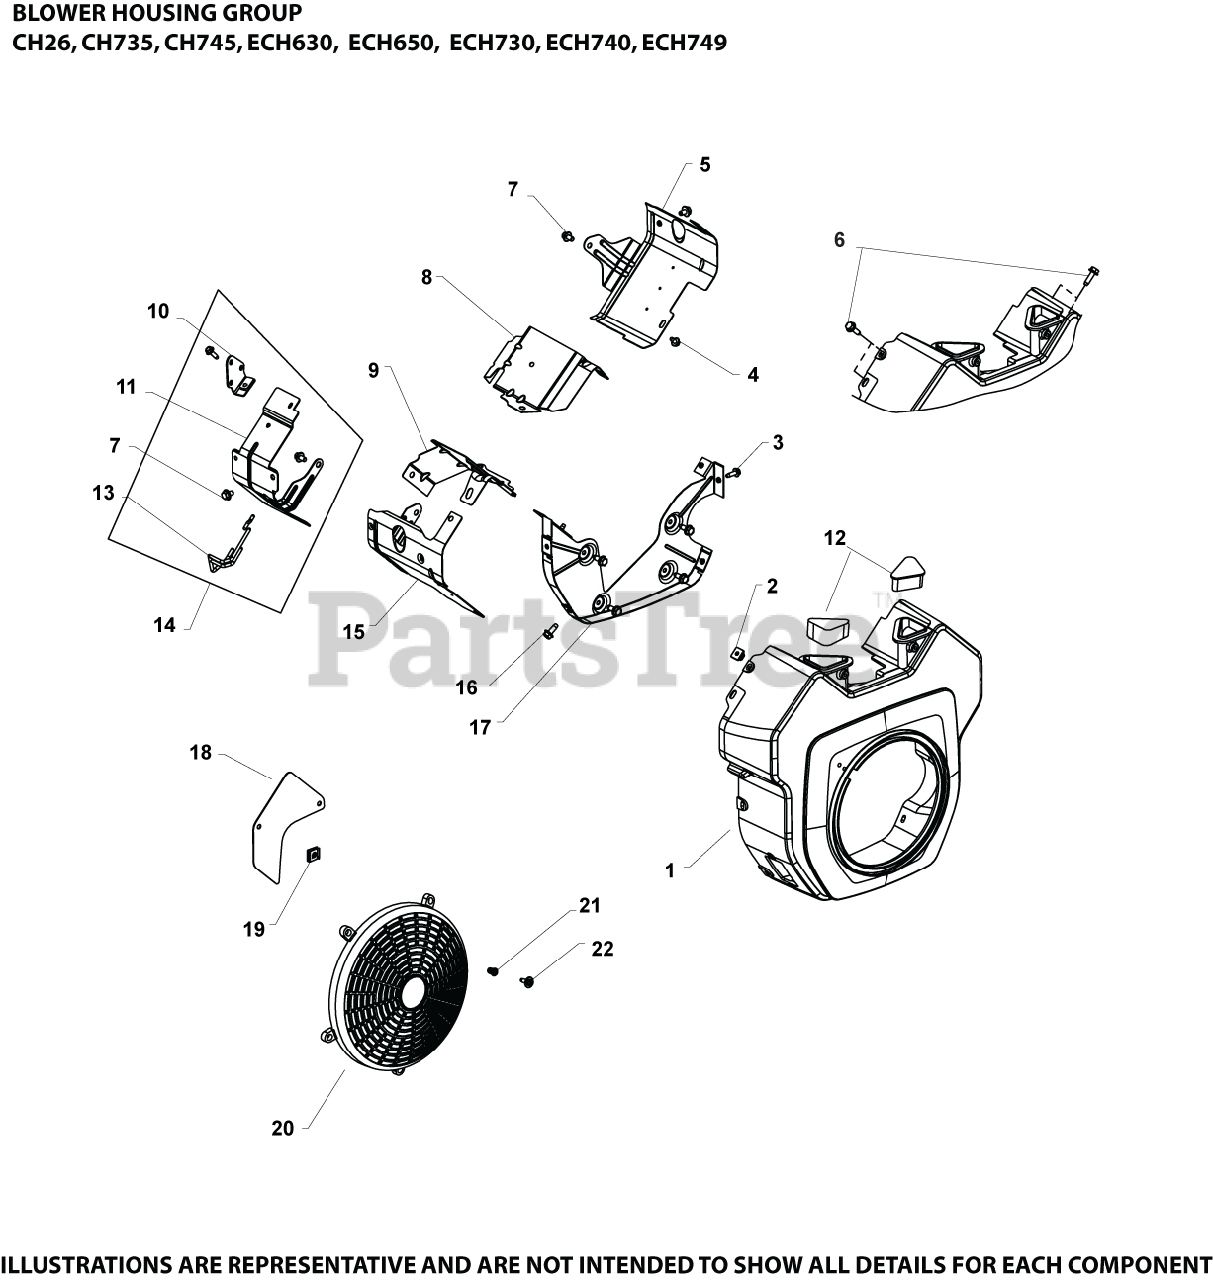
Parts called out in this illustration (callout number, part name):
1	HOUSING, BLOWER
3	SCREW, THREAD FORMING
4	SCREW, THREAD FORMING
5	BAFFLE, BARREL
6	SCREW, THREAD FORMING
8	BAFFLE, VALLEY #1 CYLINDER
9	BAFFLE, VALLEY #2 CYLINDER
12	COVER, BLOWER HOUSING USE 24 096 160-S
15	BARREL, LEFT BAFFLE-(#24063112S)
16	SCREW, THREAD FORMING
17	PLATE, BACKING
20	KIT, FIXED GUARD
21	INSERT, THREADED USE 25 332 19-S
22	SCREW, SEMS
2445501-S	TOOL, INSERT INSTALLATION
